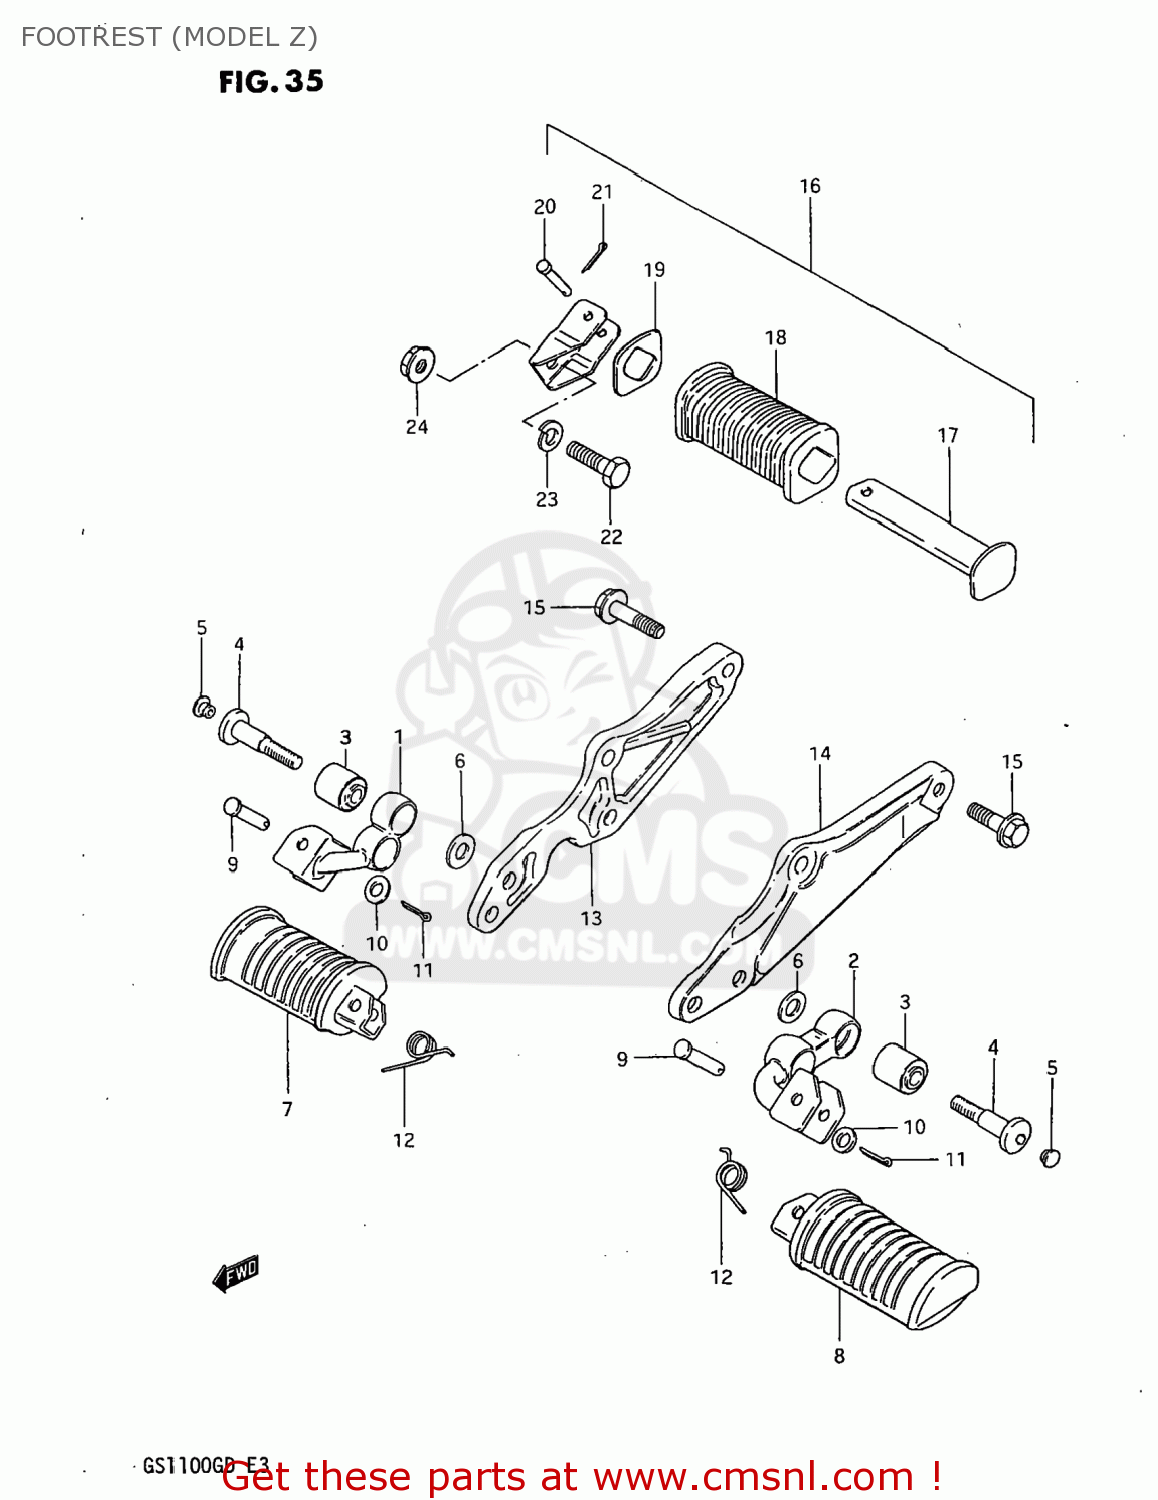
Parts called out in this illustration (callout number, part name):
1	BAR,FRONT FOOTREST,RIGHT
2	BAR,FRONT FOOTREST,LEFT
3	BUSH
4	BOLT(10X50)
5	CAP
6	WASHER
7	RUBBER,PILLION FOOTREST,R
8	RUBBER,PILLION FOOTREST,L
9	PIN
10	WASHER
11	PIN 20X20
12	SPRING
13	BRACKET,MUFFLER,RIGHT
14	BRACKET,MUFFLER,LEFT
15	BOLT
16	FOOTREST ASSEMBLY,REAR
17	BAR,REAR FOOTREST
18	RUBBER,REAR FOOTREST
19	WASHER,REAR FOOTREST RUBBER
20	PIN
21	PIN 20X20
22	BOLT,M10X1.25X
23	LOCK WASHER
24	NUT
